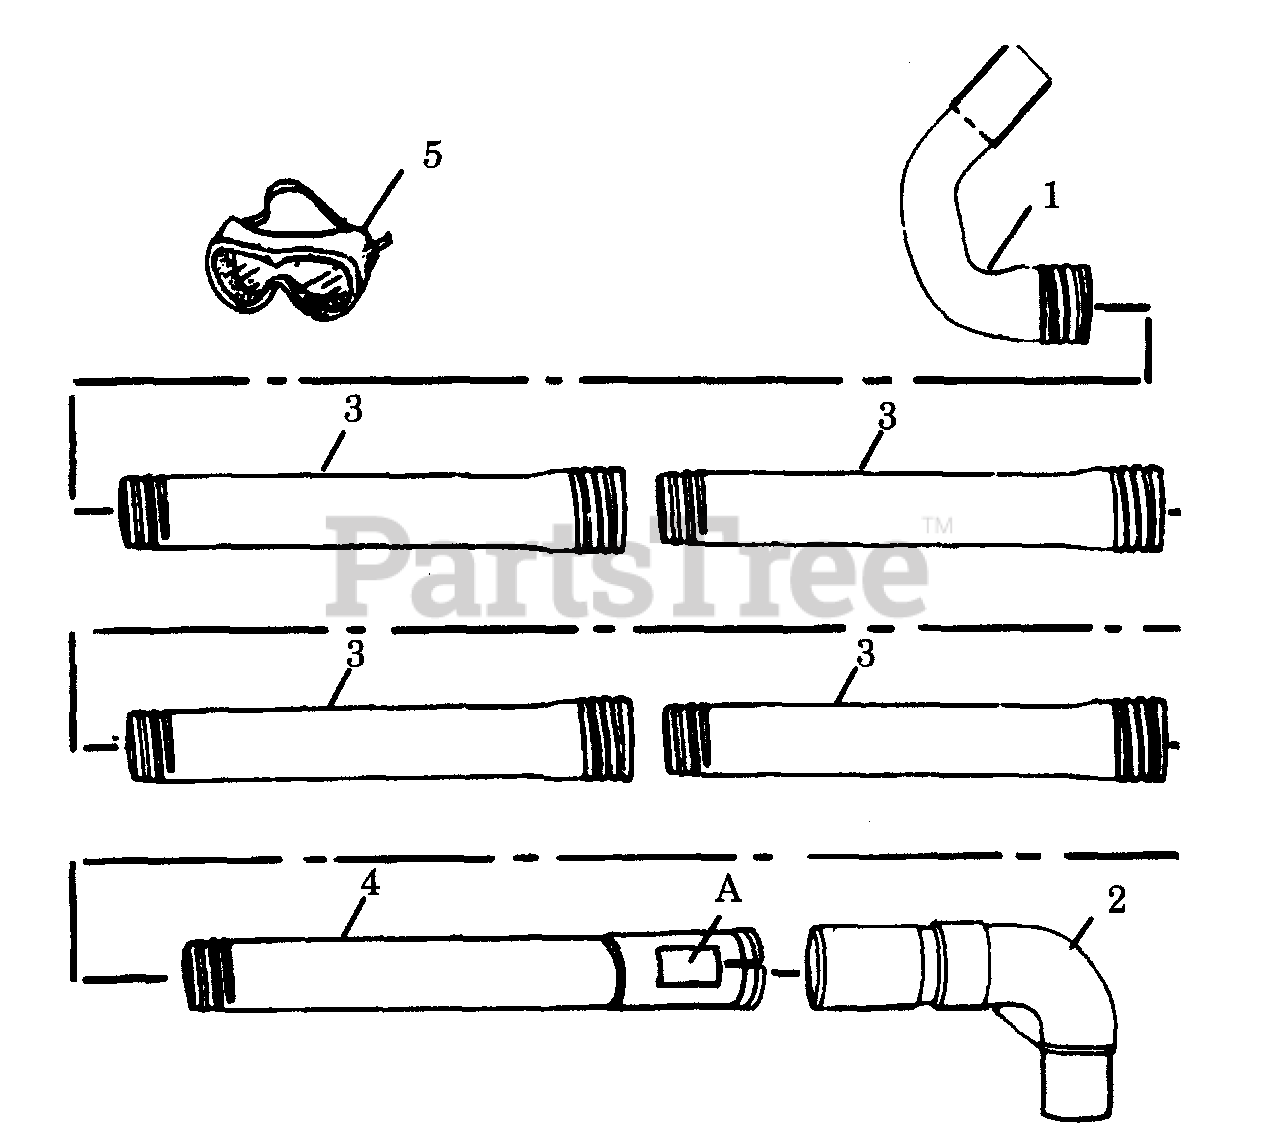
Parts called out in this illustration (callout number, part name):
3	Extension Tube
4	Pivot Tube
5	Goggles
A	Warning Decal
